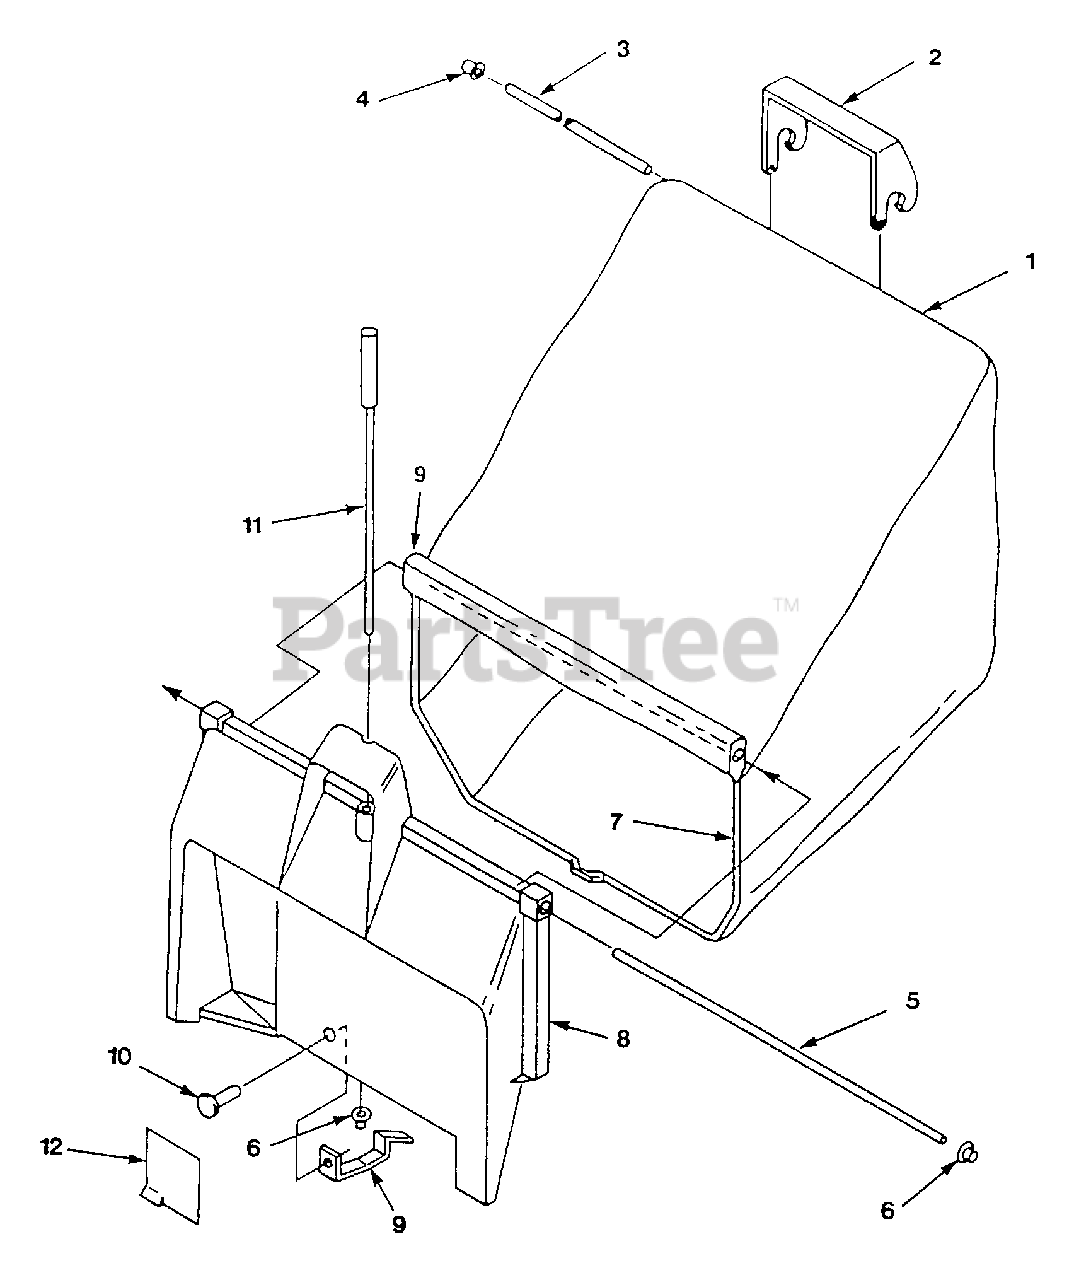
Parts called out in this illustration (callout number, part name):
1	Bag - grass catcher
2	Handle - bag
3	Rod - handle
4	Retainer - handle rod
5	Rod - bag hinge
6	Nut - Pal
7	Frame - bag, unshaped
8	Adapter - bag
9	Latch - bag release
10	Rivet - pop
11	Rod - latch release
12	Decal - heat deflector
